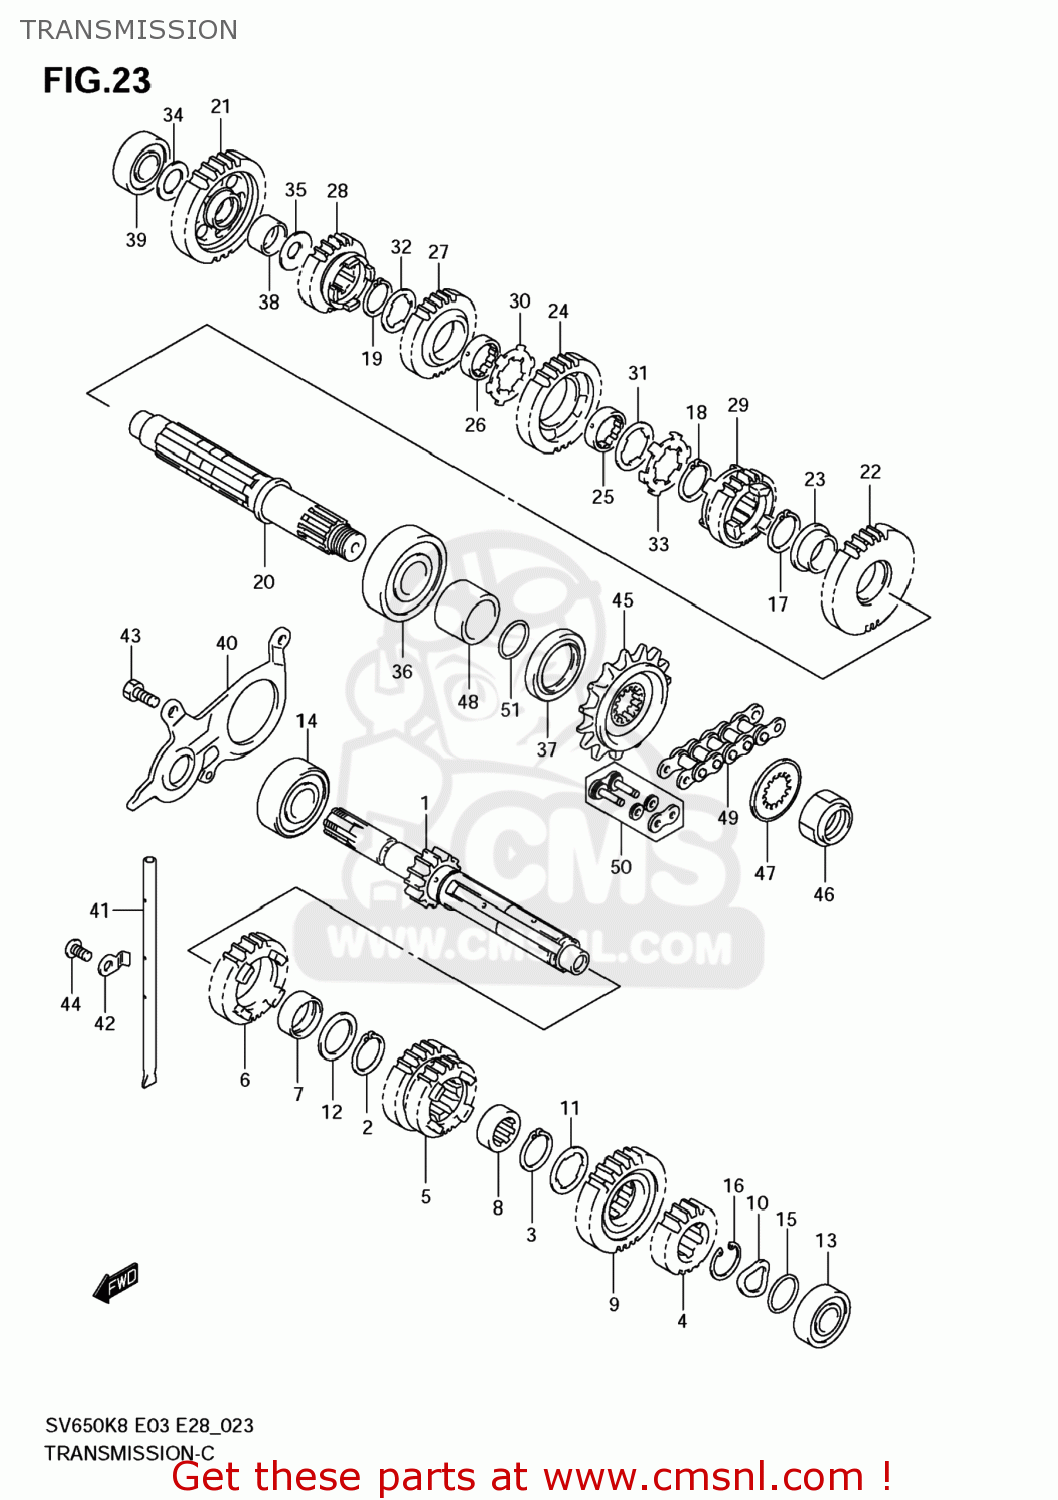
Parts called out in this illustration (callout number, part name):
1	SHAFT,COUNTER
2	CIRCLIP
3	CIRCLIP
4	GEAR,SECOND DRIVE (NT:18)
5	GEAR,3RD & 4TH
6	GEAR,5TH DRIVE(NT:26)
7	BUSH
8	BUSH,6TH DRIVE GEAR
9	GEAR,6TH DRIVE(NT:27)
10	WASHER
11	WASHER,LOCK
12	SHIM(25X34X1)
13	BEARING(17X40X12)
14	BEARING(20X52X15)
15	O RING(D:1,ID:16.8)
16	CIRCLIP
17	CIRCLIP
18	CIRCLIP
19	CIRCLIP
20	SHAFT,DRIVE
21	GEAR,1ST DRIVEN(NT:32)
22	GEAR,2ND DRIVEN.NT:32)
23	BUSH
24	GEAR,3RD DRIVEN(NT:29)
25	BUSH,DRIVEN GEAR
26	BUSH,DRIVEN GEAR
27	GEAR,4TH DRIVEN(NT:27)
28	GEAR,5TH DRIVEN(NT:25)
29	GEAR,6TH DRIVEN(NT:23)
30	WASHER,LOCK
31	WASHER,LOCK
32	WASHER,LOCK
33	WASHER
34	SHIM(17X28X1)
35	SHIM(20X30X1)
36	BEARING(25X62X17)
37	SEAL,OIL(36X50X6)
38	BUSH(20X24X13)
39	BEARING(17X40X12)
40	RETAINER,DRIVESHAFT O
41	GUIDE,T/M OIL
42	RETAINER,TRANSMISSION OIL
43	BOLT
44	SCREW
45	SPROCKET,ENGINE(NT:15)
46	NUT
47	WASHER,LOCK
48	SPACER,ENGINE SPROCKET
49	CHAIN,DRIVE(525V9X114LE)
50	JOINT SET,CHAIN
51	O RING(D:2.4,ID:23.7)
